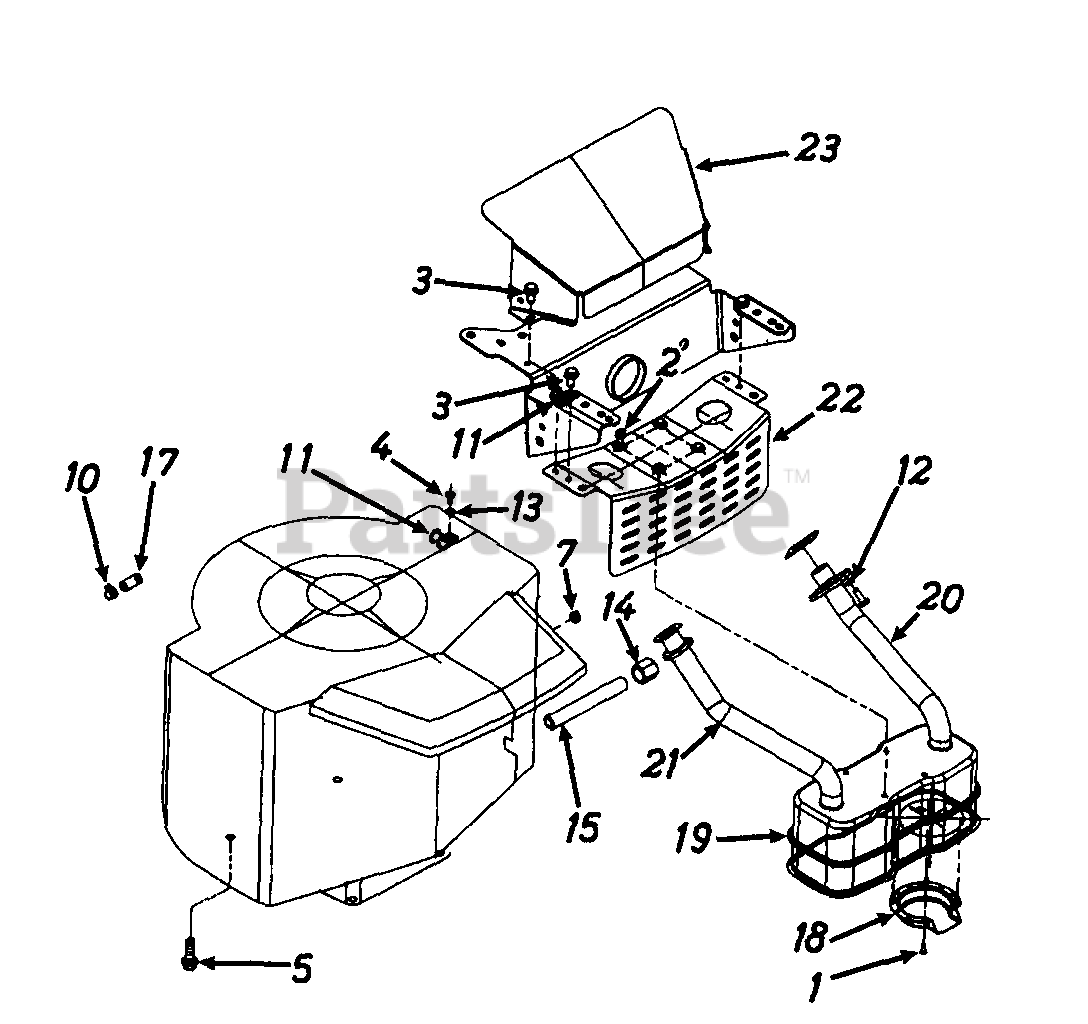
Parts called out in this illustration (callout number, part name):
1	Hex Tap Scr. #8-32 x .38" Lg.
2	Hex Wash. TT-Tap Scr. 1/4-20 x .5" Lg.
3	Hex Wash. TT-Tap Scr. 5/16-18 x .62" Lg.
4	Truss Mach. Scr. #10 x .5" Lg.
5	Hex Hd. Tap Scr. 3/8-16 x 1.25" Lg.
7	Hex Sems Nut 1/4-20 Thd.
10	Hose Clamp
11	Clamp
12	L-Wash. 1/4" I.D.
13	Fl-Wash. .188" I.D. x .438" O.D.
14	Oil Drain Cap
15	Pipe Nipple 3/8 x 18 NPT.
17	Fuel Line 26" Lg.
18	Deflector: Muffler
19	Muffler
20	Exhaust Pipe - L.H.
21	Exhaust Pipe - R.H.
22	Muffler Bracket
